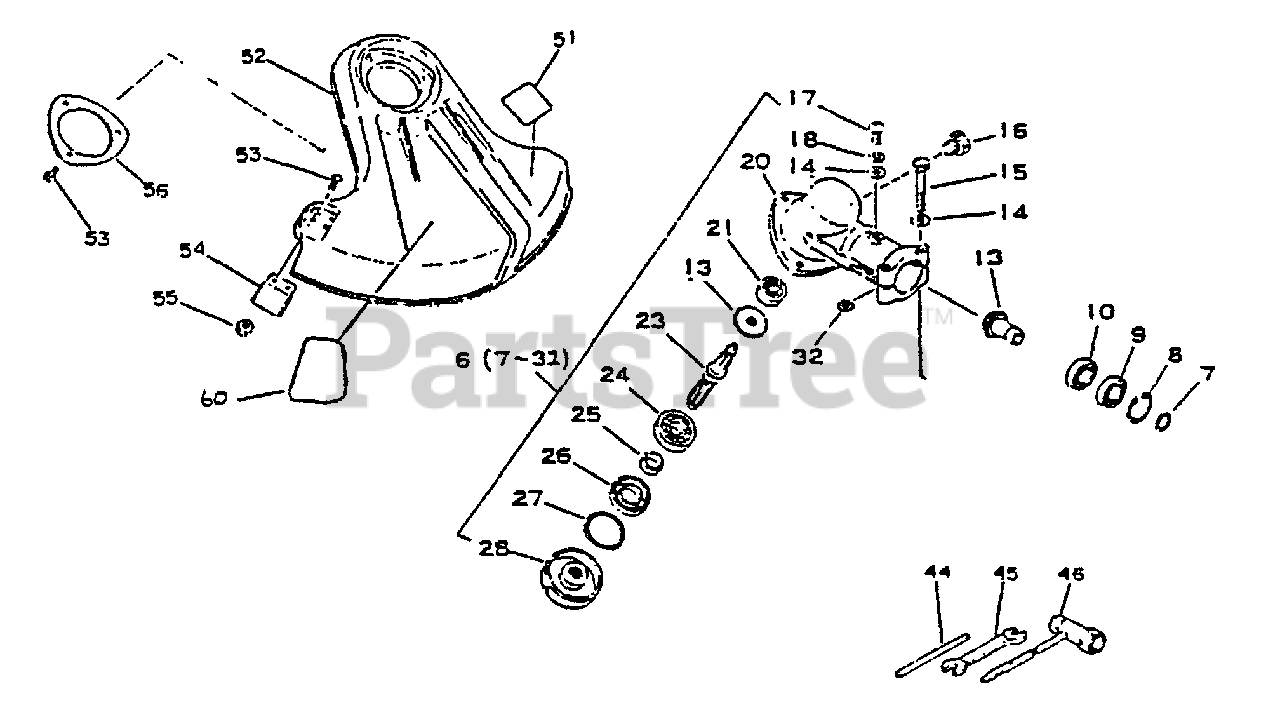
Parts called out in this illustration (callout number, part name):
6	GEAR CASE ASSY
7	RING, RETAINING - 12
8	RING, RETAINING - 22
9	BEARING, BALL - 6900Z
10	BEARING, BALL - 6900
13	GEAR SET - BEVEL
14	WASHER - 5
15	BOLT - 5X35
16	BOLT - 8X8
17	SCREW - 5X10
18	LOCKWASHER - 5
20	CASE, GEAR
21	BEARING, BALL - 609
23	GEAR - SHAFT
24	BEARING, BALL - 6201
26	SEAL, OIL
27	RING, RETAINING - 32
28	ADAPTOR, BLADE - UPPER
44	LOCKING TOOL
45	SPANNER - 8X10mm
46	T-WRENCH - 17X19mm
51	LABEL - ECHO
52	SHIELD, DEBRIS
53	SCREW - 5X16
54	KNIFE, TRIMMER LINE
56	PLATE, SHIELD
60	LABEL - CAUTION
